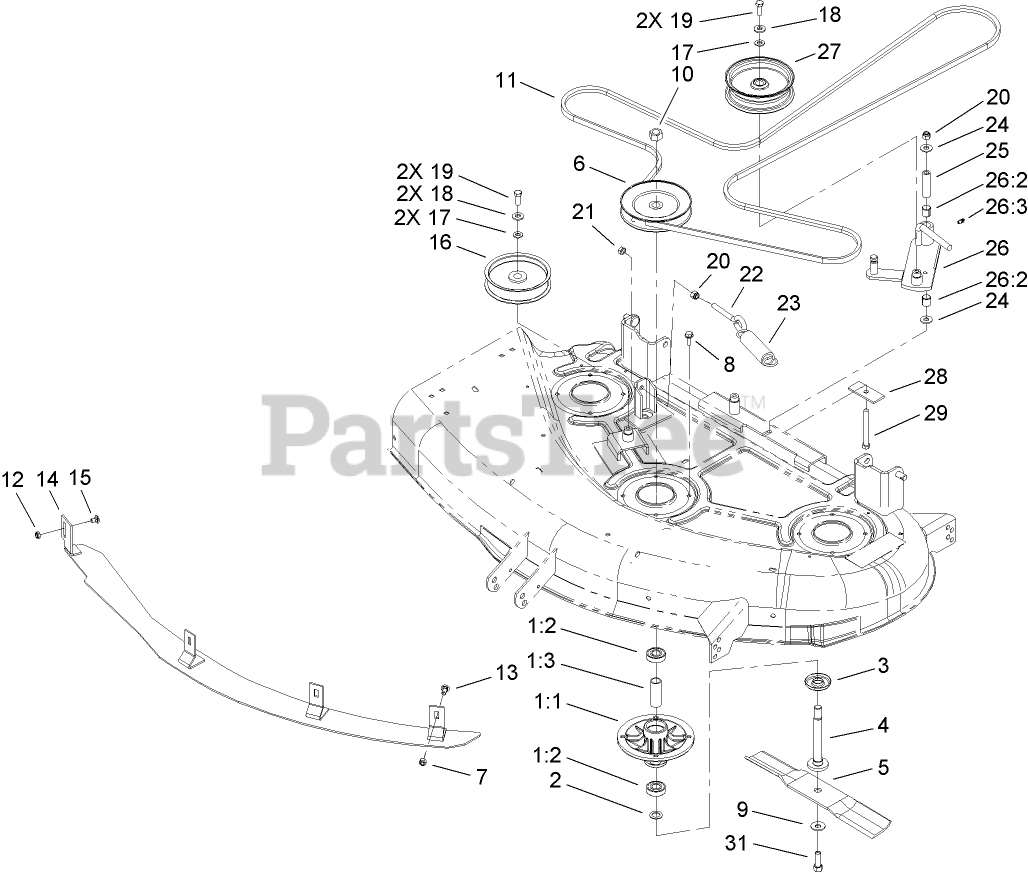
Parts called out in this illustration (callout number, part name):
1	Spindle ASM
1:1	HOUSING-SPINDLE
1:3	SPACER
2	SPACER
3	SHIELD-BEARING
4	SHAFT-SPINDLE
6	PULLEY ASM
7	NUT-LOCK, NI
8	SCREW-TAPTITE
9	WASHER-BELLEVILLE
10	NUT-HEX
11	BELT-V
12	NUT-LOCK, NI
13	BOLT-CARR
15	BOLT-CARR
16	PULLEY-IDLER
17	WASHER-FLAT
18	WASHER-BELLEVILLE
19	SCREW-HH
20	NUT-LOCK, NI
21	NUT-HEX
22	BOLT-EYE
23	SPRING-EXTENSION
24	WASHER-HARDENED
25	BUSHING-PIVOT, IDLER
26	IDLER ARM ASM
26:2	SLEEVE-BEARING
26:3	FITTING-GREASE
28	SCREW-HH
29	PLATE-BOLT, RETAINER
31	SCREW-HH
